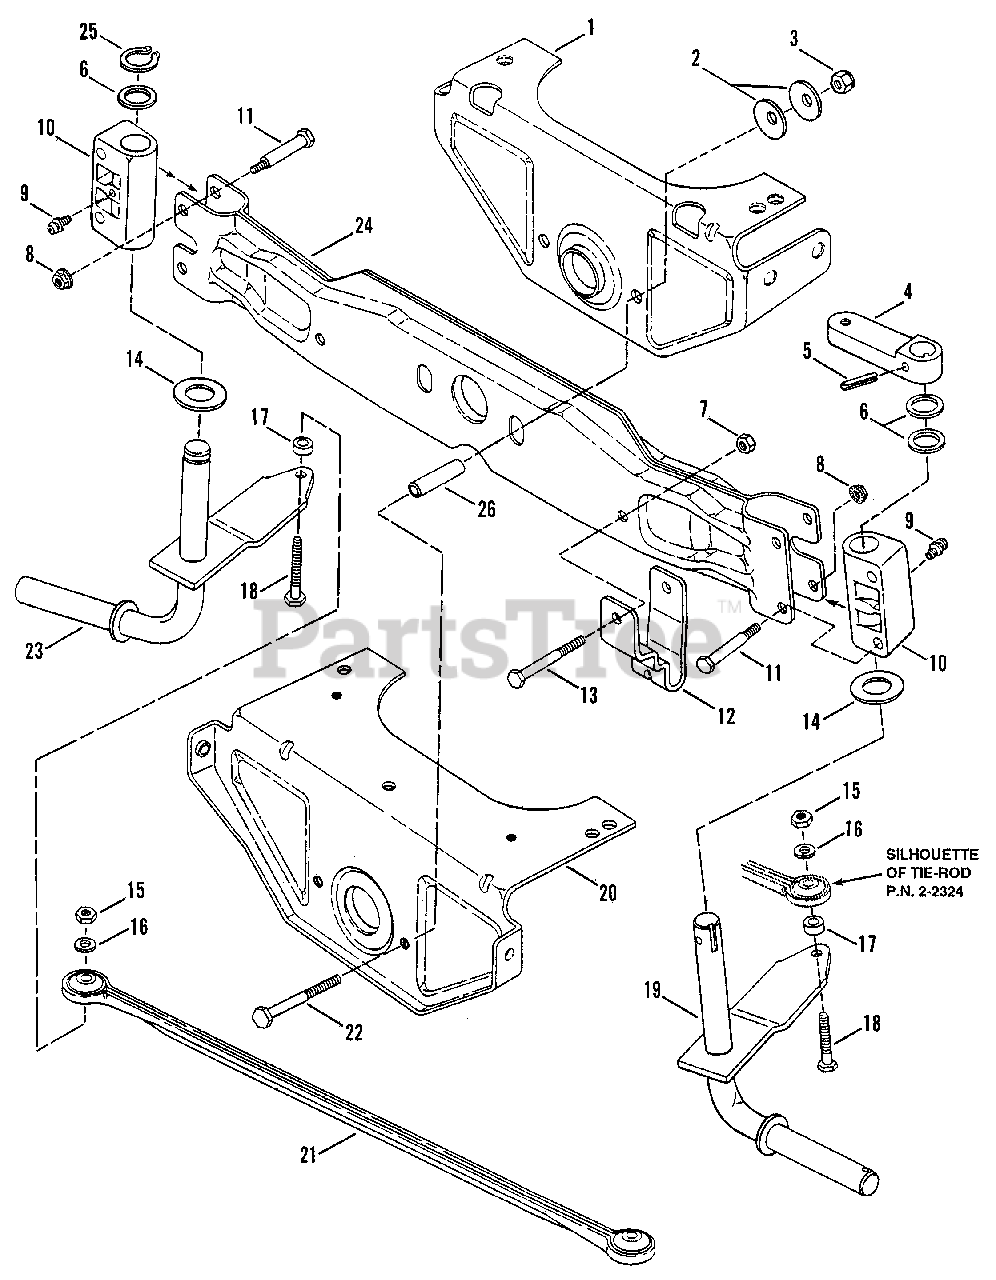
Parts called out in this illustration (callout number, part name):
1	BRACKET, Axle (Rear)
2	WASHER, Cone
3	NUT, 3/8-16 Nyloc
4	ARM, Steering
5	ROLL-PIN, 1/4 x 1 1/4"
6	WASHER, Shim
7	NUT, 5/16-18 Hex Center Lock
8	NUT, 1/4-20 Hex Flange Top-Lock
9	LUBE FITTING, Straight (press-fit for .187 dia. Hole)
10	BEARING, Spindle
11	BOLT, 1/4-20 x 1 41/64" Shoulder
12	BRACKET, Deck Hanger
13	SCREW, 5/16-18 x 2 1/2" Hex Head Cap
14	WASHER, Thrust
15	NUT, 3/8-16 Hex
16	WASHER, 3/8 Split Lock
17	SPACER, Tie-Rod
18	SCREW, 3/8-16 x 1 1/2" Hex Head Cap, Grade 5
19	SPINDLE ASSEMBLY, Left Hand
20	BRACKET ASSEMBLY, Axle (Front)
21	TIE-ROD
22	BOLT, 3/8-16 x 3" Hex Head
23	SPINDLE ASSEMBLY, Right Hand
24	AXLE, Front
25	RING, Retaining
26	SPACER
